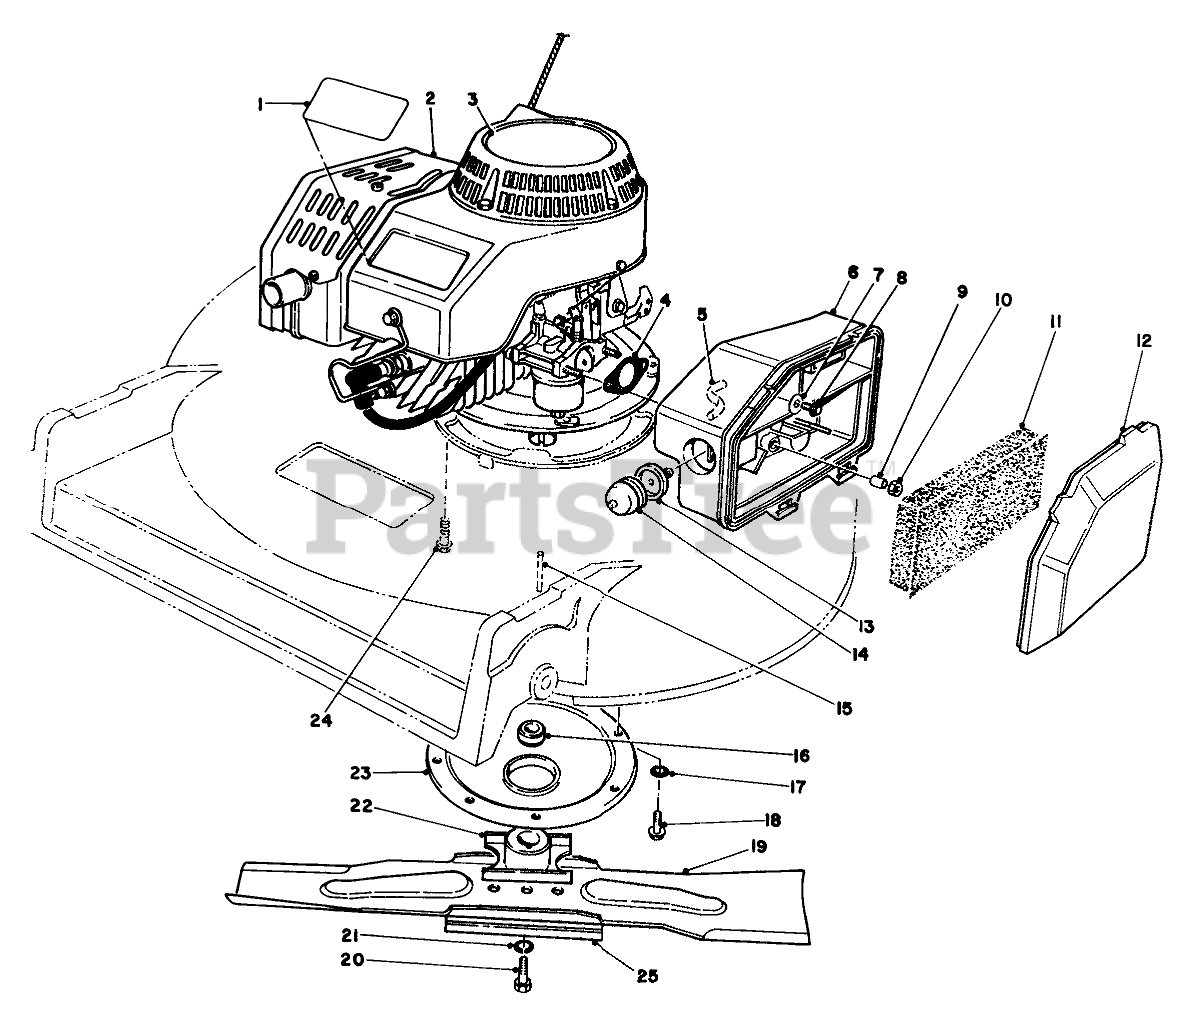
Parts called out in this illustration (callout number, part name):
1	DECAL - PROLINE
2	ENGINE ASM
3	DECAL-2 CYC RECOIL COMM
4	GASKET-AIR CLEANER
5	HOSE-PRIMER
6	BODY-AIR CLEANER
7	WASHER-FLAT
8	SCREW-HH
9	SPACER
11	ELEMENT-AIR CLEANER
12	COVER-AIR CLEANER
13	BODY-PRIMER
14	BULB-PRIMER
15	KEY-SQUARE
16	SPACER-BLADE RETAINER
17	WASHER-LOCK, INTERNAL
18	SCREW-HWHTF
19	Blade
20	SCREW-BLADE
21	WASHER-LOCK
22	RETAINER-BLADE
23	PROTECTOR-CRANKSHAFT
24	SCREW-HHF
25	Accelerator
